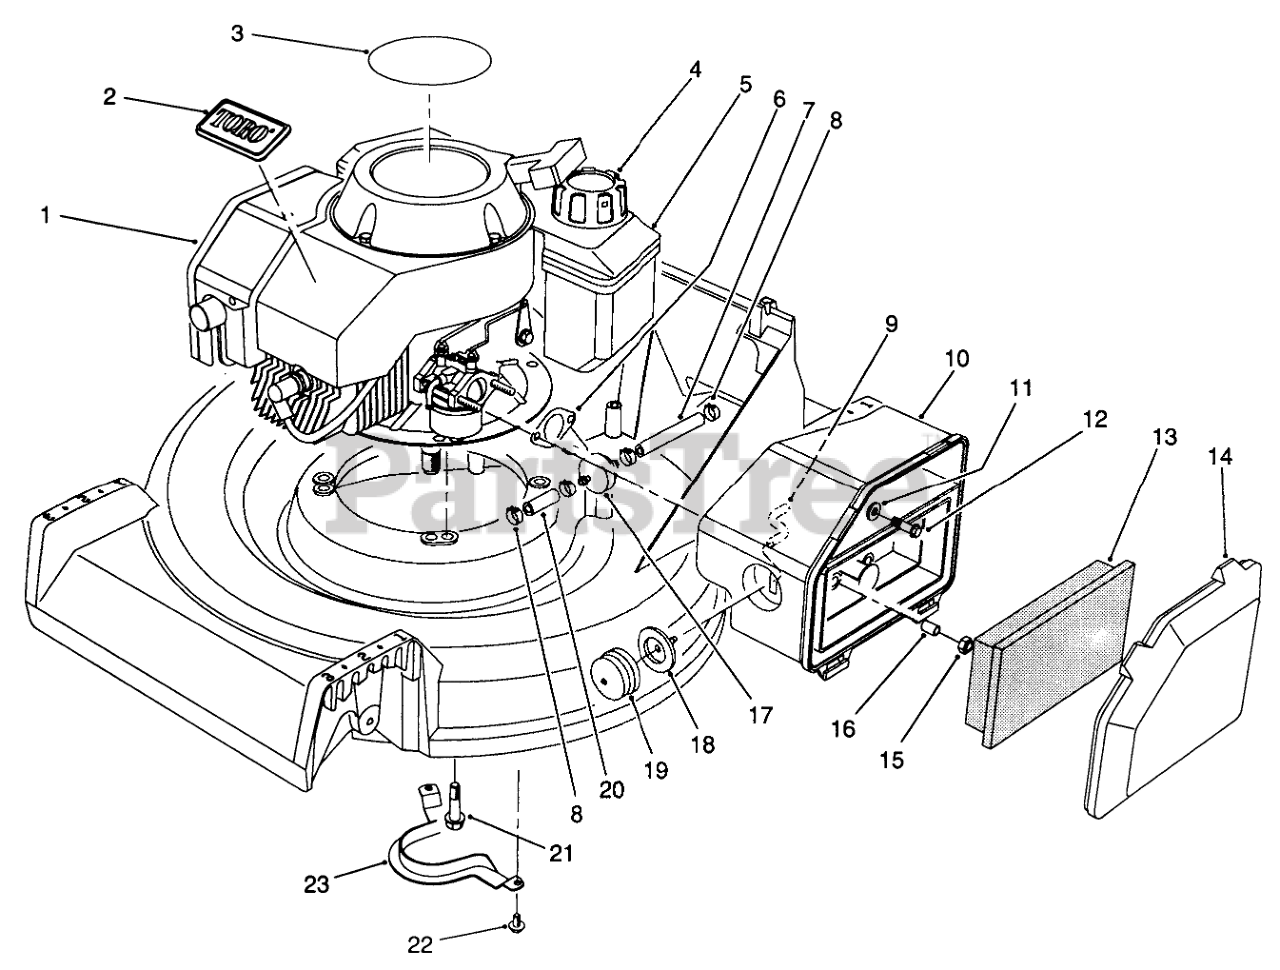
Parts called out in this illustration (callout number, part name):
1	Engine
2	TORO LOGO PLT
3	DECAL - 2 CYC RECOIL
4	GAS CAP ASM
5	FUEL TANK ASM
6	GASKET-AIR CLEANER
7	HOSE-FUEL
8	CLAMP-FUEL LINE
9	HOSE-PRIMER
10	BODY-AIR CLEANER
11	WASHER-FLAT
12	SCREW-HH
13	ELEMENT-AIR CLEANER
14	COVER-AIR CLEANER
16	SPACER
17	FILTER-FUEL
18	BODY-PRIMER
19	BULB-PRIMER
20	HOSE-FUEL
21	SCREW-HHF
22	SCREW-HWHTF
23	Guide-Belt
